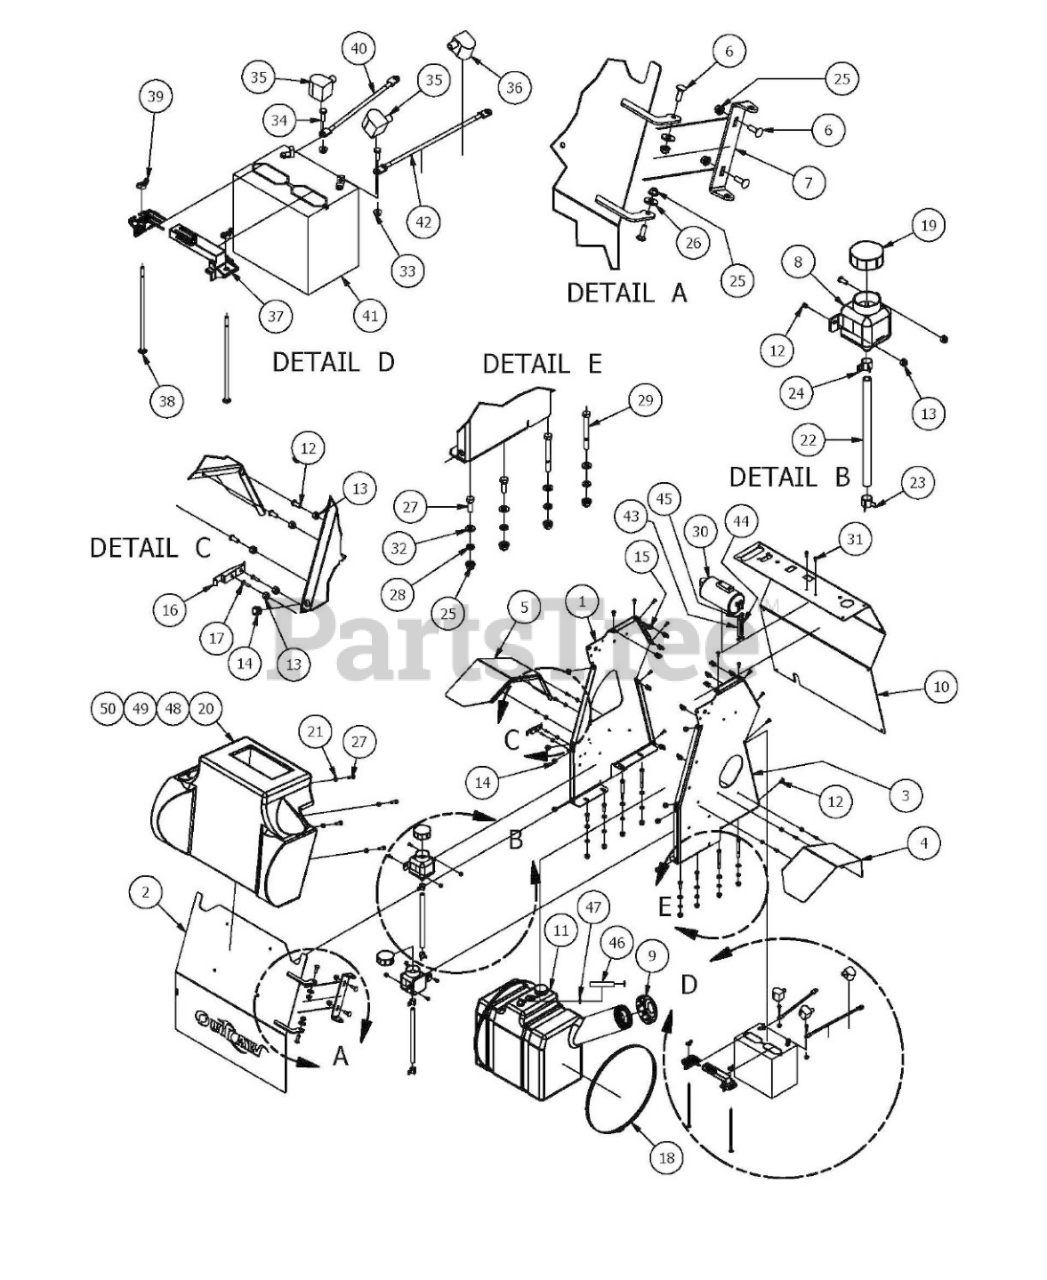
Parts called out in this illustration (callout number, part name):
1	2015 Podium Panel Left
2	Door Panel Assembly
3	2015 Podium Panel Right
4	Fender (Right Side)
5	Fender (Left Side)
6	5/16" x 1" Carriage Bolt
7	Back Cover Hinge Bracket
8	350ml Expansion Tank
10	2015 Podium Front Panel
12	1/4" x 5/8" BS C/S 18-8 SS
13	1/4" Nylock Nut
14	5/8 Round Insert
15	1/4-20 Cage Nut
16	Steel Pump Cover Latch
17	10-24 X 5/8 BS Button Head Bolt
18	Fuel Tank Clamp-Stand On
19	Hydraulic Tank Cap
20	Cushion-2015 Stand On Mower
21	1/4" Flat Washer
22	3/8" Clear Hose
23	1/2 Hose Clamp
24	3/8" Hose Clamp
25	5/16" Nylock Flange Nut Zinc
26	.360 ID Plastic Washer
27	5/16" x 1" Bolt
28	5/16" Lock Washer
29	5/16" x 3" Hex Bolt
30	Carbon Canister
31	M6-1.0 X 16MM Hex Bolt
32	5/16" Flat Washer
33	1/4-20 Hex Flange Nuts Zinc w/Serrations
34	1/4-20 x 3/4 GR 5 Hex Bolts Zinc
35	Black Boot For Ground Cable
37	Battery Hold Down
38	1/4-20 X 8 Carriage Bolt
39	1/4" Wing Nut
40	Ground Cable
42	24" Red Battery Cable
43	1/4" Vinyl Tubing
44	3/16 Vinyl Tubing
45	3/16 Vinyl Clamp
46	1/4 Fuel Line
47	1/4 Fuel Hose Clamp
48	Cup Holder
49	Cup Holder Drain Tube
50	Plastic Tray
